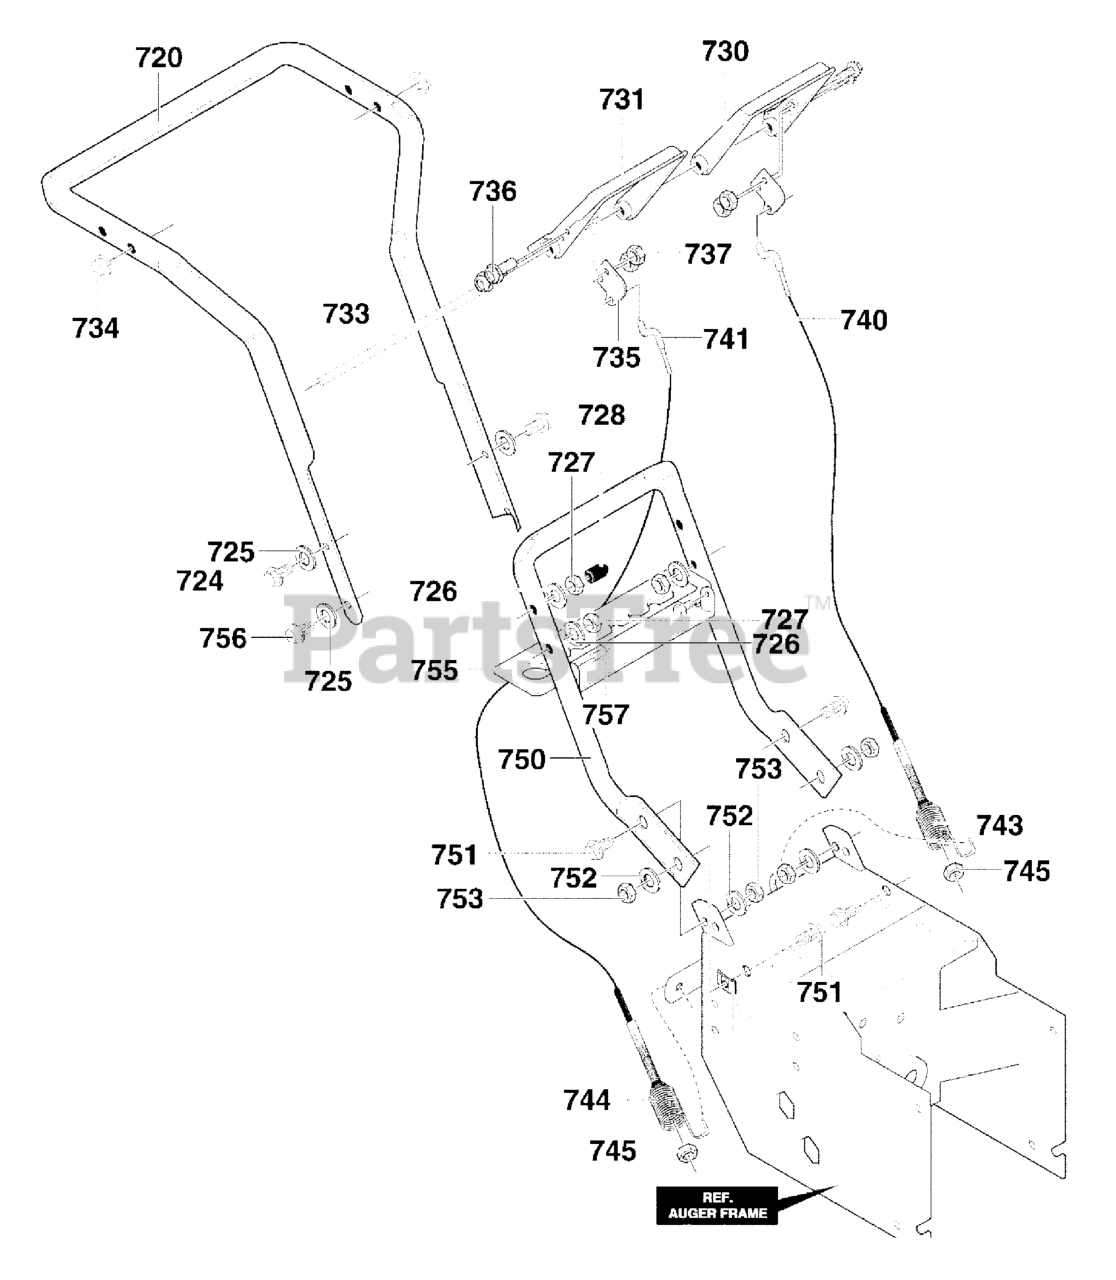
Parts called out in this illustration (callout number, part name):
720	HANDLE, UPPER
724	SCREW, 5/16-18 x 2.75
725	WASHER, FLAT
726	WASHER, SPTLK
727	NUT, 5/16-18 REGHEX
728	STOP, RED PLASTIC
730	LEVER, BAIL LH
731	LEVER, BAIL RH
733	ROD, PIVOT
734	NUT, PUSH ON
735	PLATE, CLUTCH
736	SCREW, 1/4-20 X .88
737	NUT, 1/4-20 REGHXCTRLK
740	CABLE, CLUTCH
741	CABLE, AUGER CLUTCH
743	SPRING, TENSION
744	SPRING, AUGER CLUTCH
745	NUT, 1/4-20
750	HANDLE, LOWER
751	CAPSCREW, Hex Head, 5/16-18 x 1
752	WASHER, SPTLK
753	NUT, 5/16-18 REGHEX
754	PUSHNUT, 5/16
755	BRACKET, GEAR SEL
756	SCREW, 5/16-18 x 2.00
757	SCREW, PLASTITE
